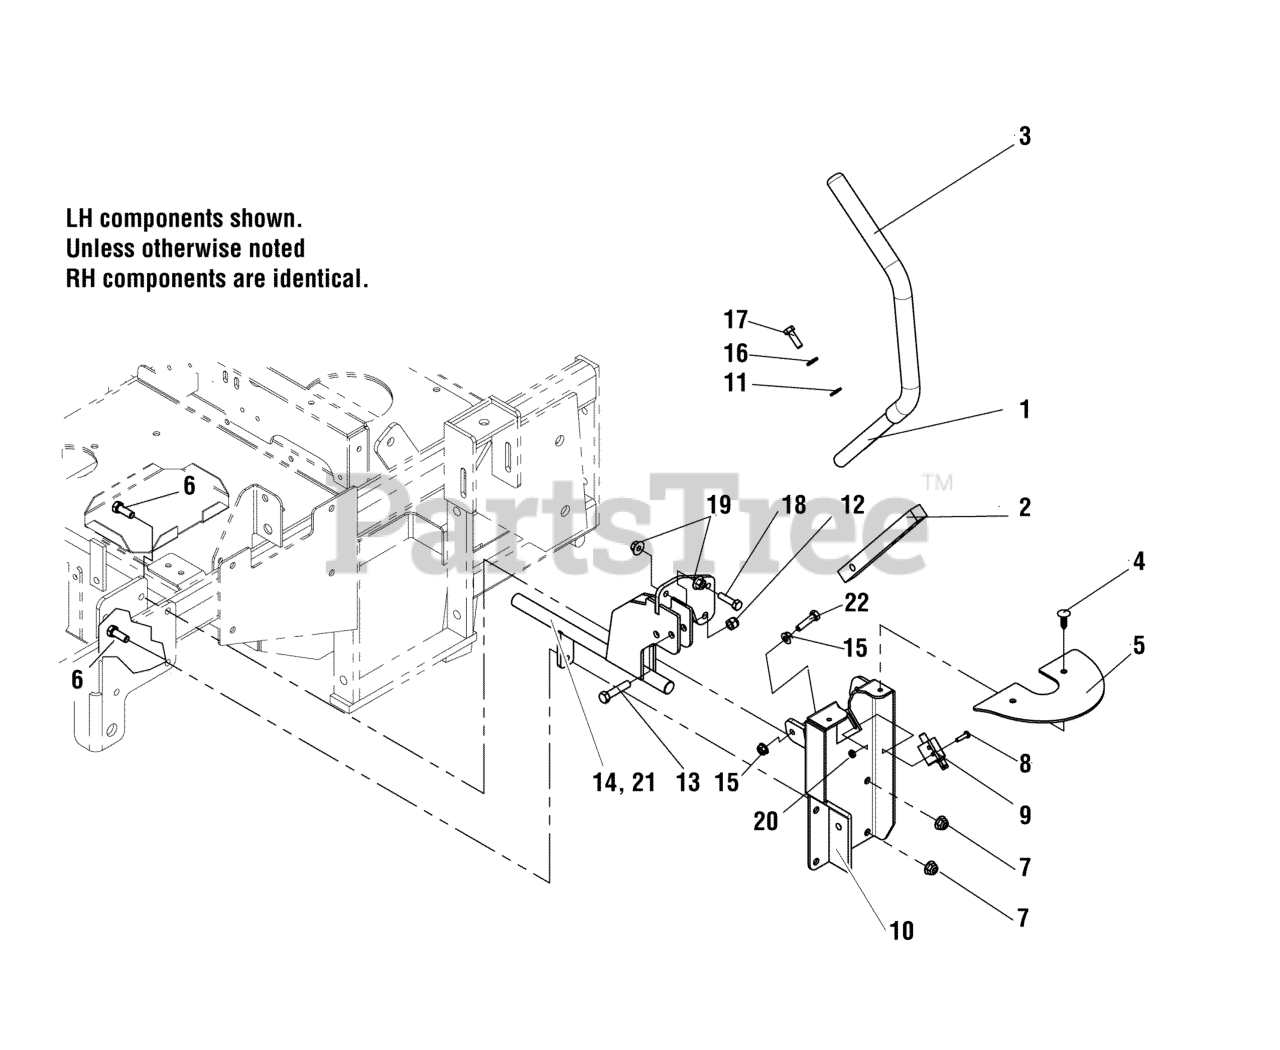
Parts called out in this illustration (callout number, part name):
1	WELD, MOTION CONTROL HANDLE, LH - BLK
1	WELD, MOTION CONT. HANDLE-RH-3000 - BLK
2	MOUNT, CONTROL ARM - BLK
3	GRIP, FOAM, 3/4" ID, 16" LONG
4	PUSH RIVET (TREE TYPE) BLACK
5	RUBBER FLAP, CONTROLS
6	BOLT, 3/8-16 X 1" GD5 CZ
7	NUT, 3/8-16 HEX NYLOCK FLANGE
8	SCREW, #10-24 X 1/2"
9	SWITCH PLUNGER N.O.
10	WELD, NEUTRAL LOCK, LH - BLK
10	WELD, NEUTRAL LOCK, RH - BLK
11	WASHER, 5/16" SAE
12	NUT, 3/8-16 HEX NYLOCK FLANGE
13	BOLT, 3/8-16 X 1-3/4" GD5 CZ
14	WELD, CONTROL SHAFT, LH 3000 - RED
14	WELD, CONTROL SHAFT, RH 3000 - RED
15	NUT, 5/16-18 HEX SERRATED FLANGE (SMALL)
16	WASHER, 5/16 LOCK CZ
17	BOLT, 5/16-18 X 1" GD5
18	BOLT, 5/16-18 X 1-1/4" GD5
19	NUT, 5/16-18 HEX SERRATED FLANGE (LARGE)
20	10-24 HEX NUT
21	WELD, CONTROL SHAFT, LH 3000 - BLK
21	WELD, CONTROL SHAFT, RH 3000 - BLK
22	5/16-18 X 1-3/4, TFL
